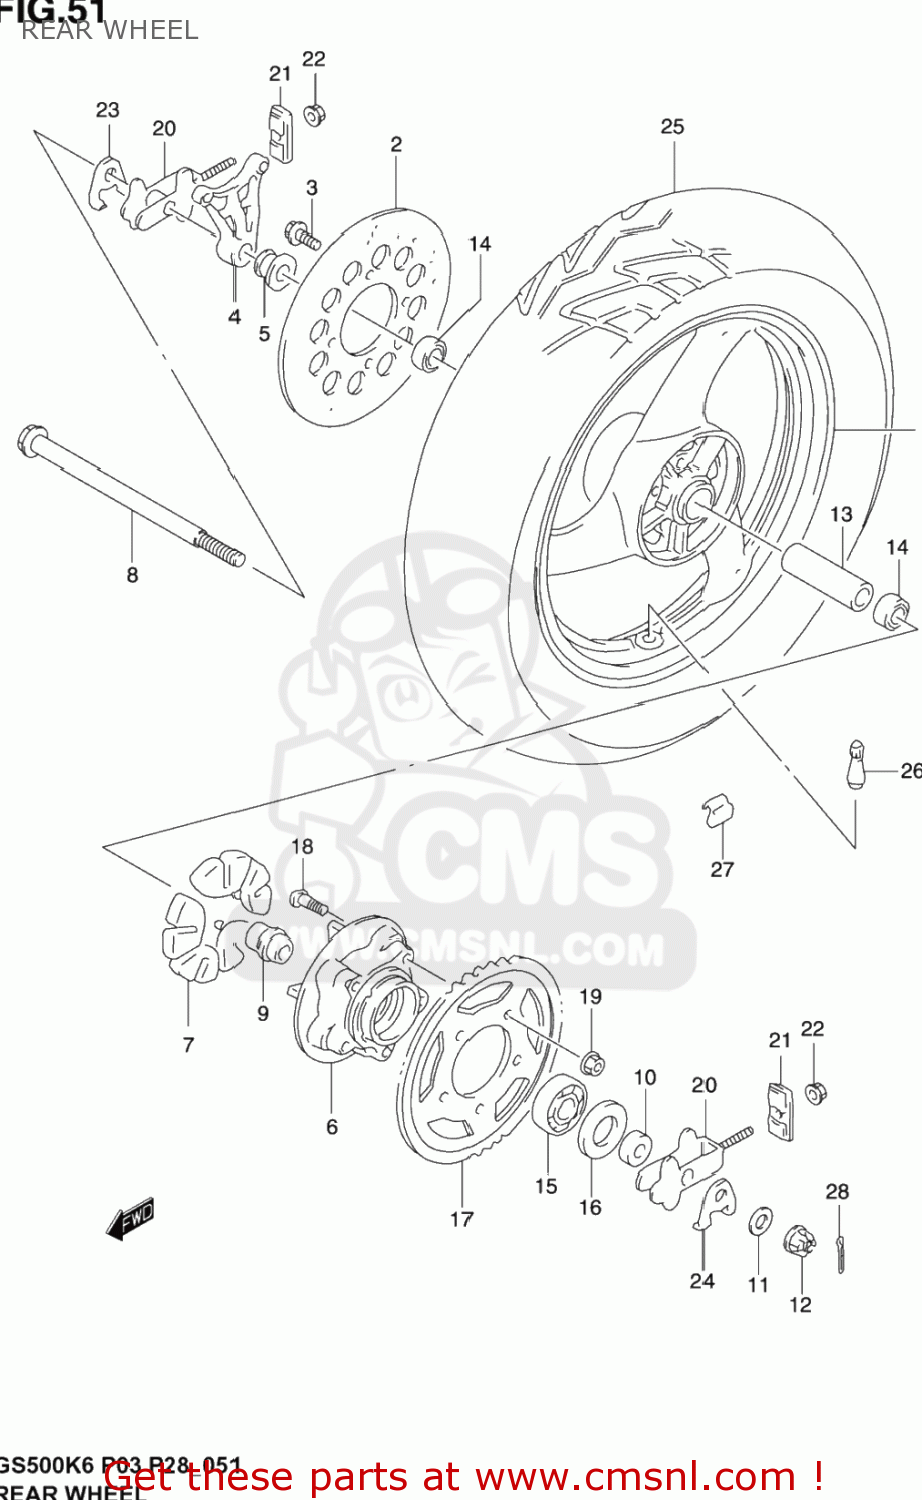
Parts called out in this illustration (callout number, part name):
1	WHEEL,RR(MT3.50X17)
2	DISC REAR BRAK
3	BOLT(8X30)
4	BRACKET,CALIPE
5	SPACER, REAR AXLE RH
6	DRUM, REAR SPROCKET
7	ABSORBER,RR HUB SHOCK
8	AXLE,RR
9	RETAINER, DRUM
10	SPACER, REAR AXLE LH
11	WASHER(17X30X3)
12	NUT
13	SPACER(17.5X25X88)
14	BEARING
15	BEARING(25X62X17)
16	SEAL,OIL(35X62X8)
17	SPROCKET, REAR (NT:39)
18	BOLT
19	NUT
20	ADJUSTER, CHAIN
21	PLATE, GUIDE
22	NUT
23	WASHER,CHAIN A
24	WASHER, CHAIN ADJUSTER LH
25	TIRE, REAR (130/70-17M/C 62H)
26	VALVE
27	BALANCER,WHEEL(10G)
28	PIN,COTTER
